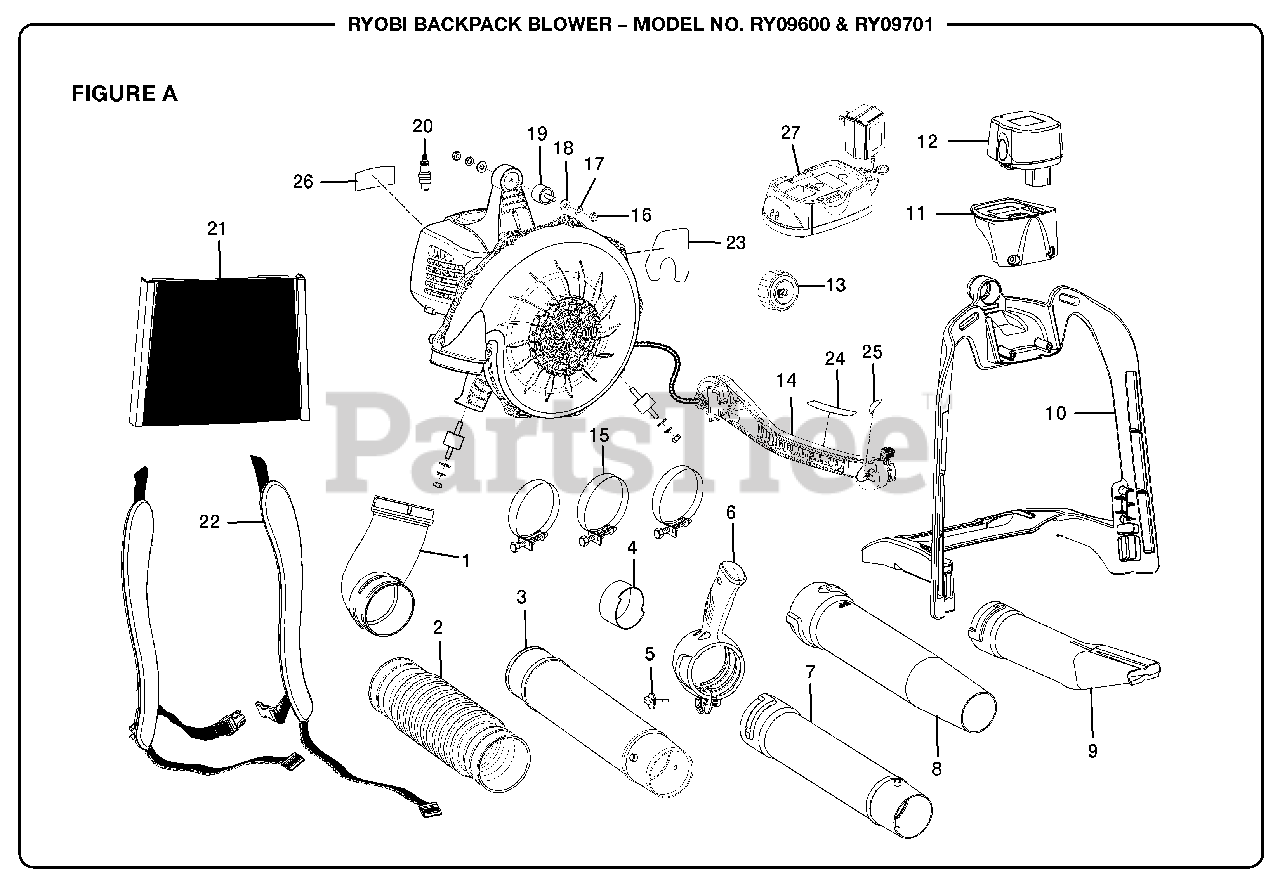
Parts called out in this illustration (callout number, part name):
3	Upper Tube
5	Thumb Screw
6	Adjustable Handle Assembly
7	Lower Tube
8	Nozzle
9	High Velocity Nozzle w/ Leaf Scraper
11	Battery Receiver
12	12V Battery
13	Fuel Cap Assembly
14	Throttle Arm Assembly
15	Tube Clamp
16	Hex Nut (1/4-20)
17	Lock Washer
19	Vibration Isolators
20	Spark Plug
21	Mesh Backing
22	Harness Assembly
23	Starting Label
24	Warning Label
25	Touch Start Label
26	Logo Label
